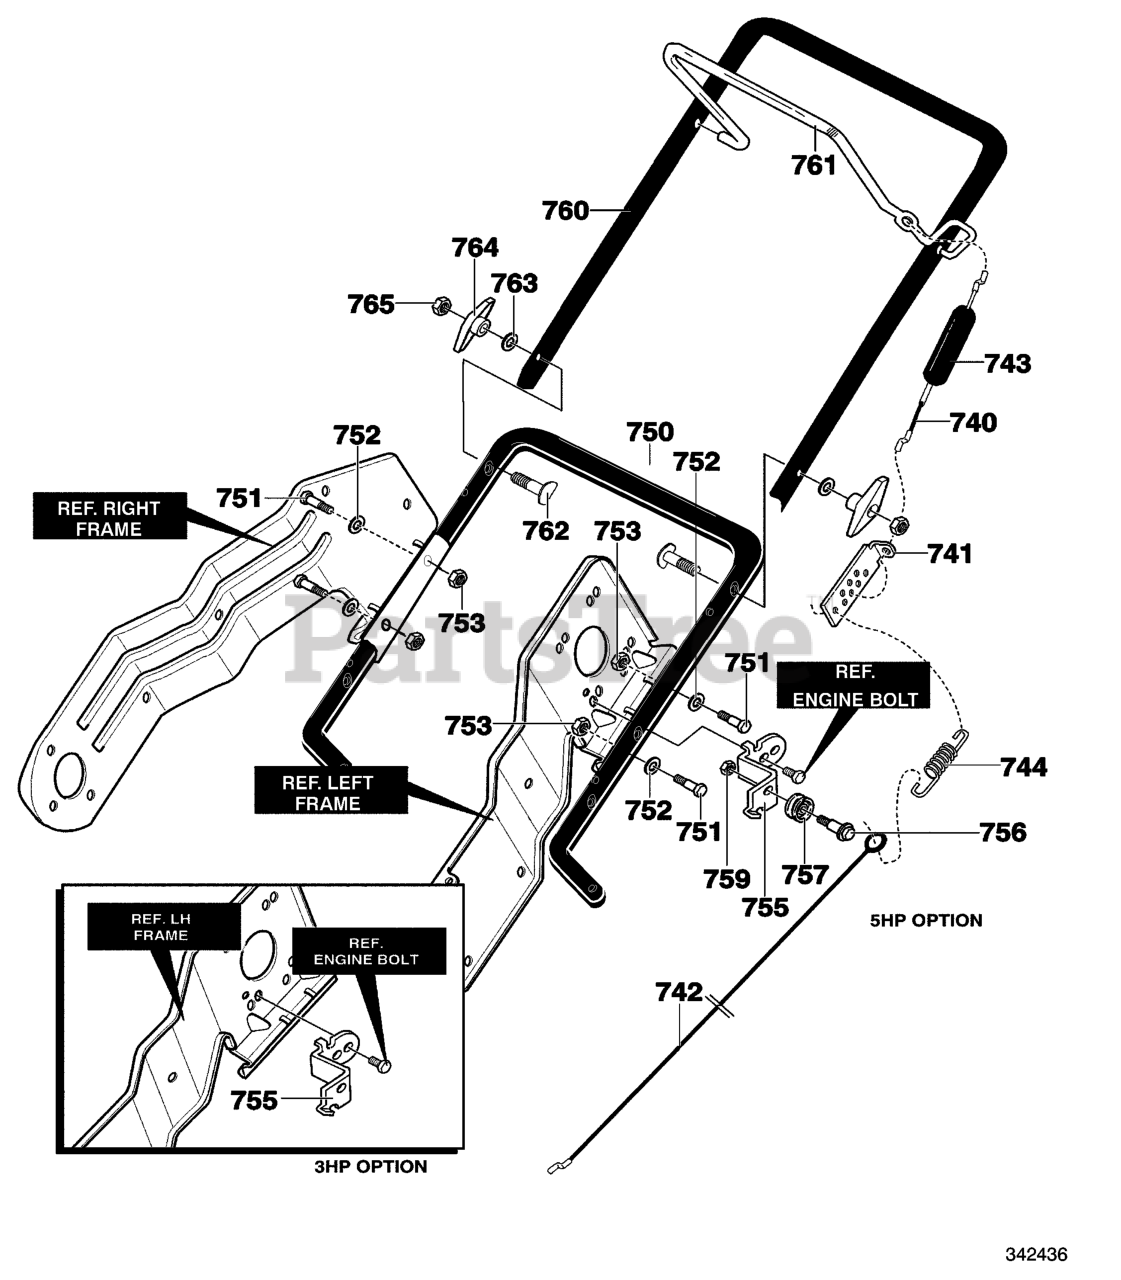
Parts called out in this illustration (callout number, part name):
740	CABLE, UPPER
741	BRKT, CABLE ADJ
742	CABLE LOWER CONTROL
743	BOOT, CLUTCH SPRING
750	HANDLE LOWER
751	SCREW, 1/4-20X1.25
752	WASHER, FLAT .281X.63X.065
753	NUT, 1/4-20 REGHEXCTRLK
755	BRACKET, CABLE
756	BOLT, .375X.375 1/4-20
757	PULLEY, .906X.305
759	NUT, 1/4-20 REGHEXCTRLK
760	HANDLE, UPPER
761	BAIL, CONTROL
762	BOLT, 5/16-18X2.00
763	WASHER, FORM
764	KNOB,T
765	NUT, 5/16-18 REGHEX
